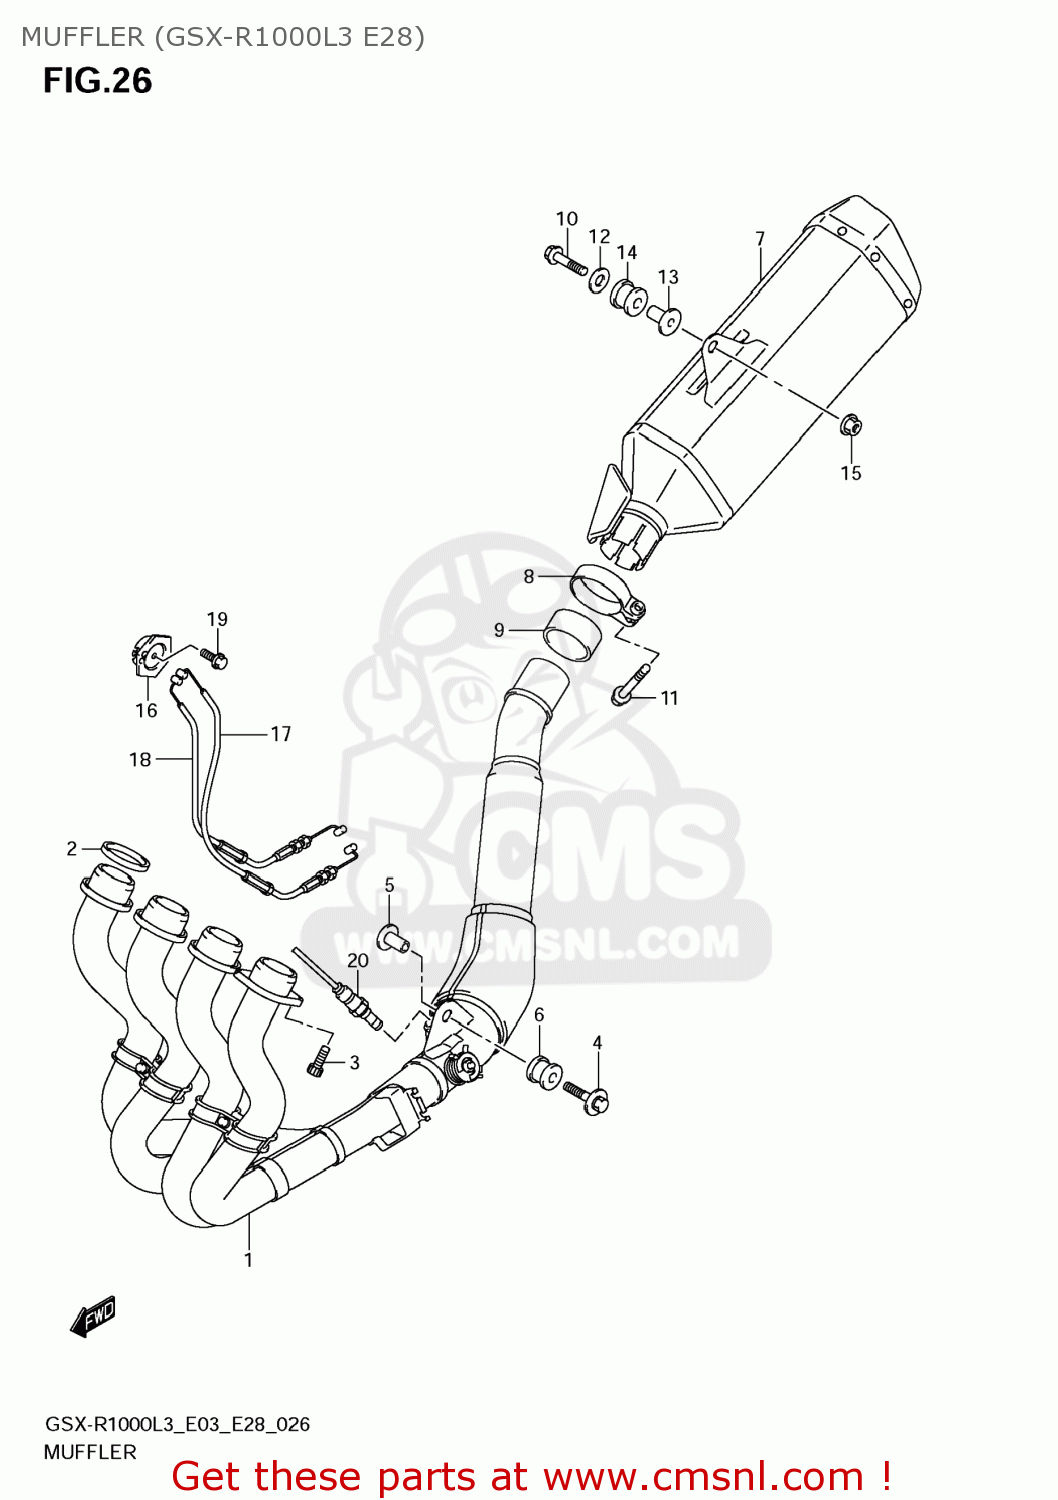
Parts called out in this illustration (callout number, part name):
1	EXHAUST
2	GASKET,EXHAUST PIPE (NAS)
3	BOLT
4	BOLT(8X45)
5	SPACER(8.6X12X24.2)
6	CUSHION
7	BODY,MUFFLER
8	CLAMP,MUFFLER CONNECTOR
9	CONNECTOR,MUFFLER
10	BOLT(8X45)
11	BOLT(8X40)
12	WASHER(8.5X28X1.5)
13	SPACER(8.6X12X24.2)
14	CUSHION
15	NUT
16	PULLEY,CONTROLLER
17	CABLE,EXHAUST VALVE NO.1
18	CABLE,EXHAUST VALVE NO.2
19	BOLT
20	SENSOR,OXYGEN
